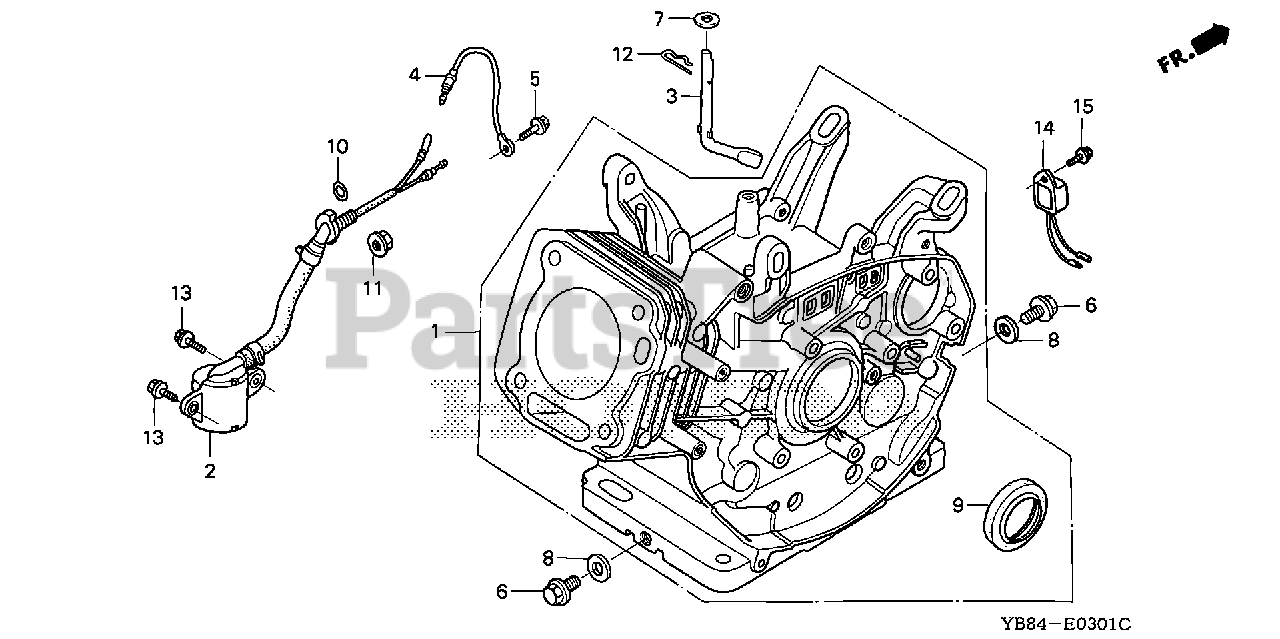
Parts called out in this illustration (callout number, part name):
1	CYLINDER ASSY. (ALERT)
2	SWITCH ASSY., OIL LEVEL
3	SHAFT, GOVERNOR ARM
4	SUB-HARNESS (NOT AVAILABLE)
5	BOLT, FLANGE (6X12) (CT200)
6	BOLT, DRAIN PLUG (12X15)
7	WASHER (8.2X17X0.8)
8	WASHER, DRAIN PLUG (12MM)
9	OIL SEAL (30X46X8)
10	O-RING (13.5X1.5) (ARAI)
10	O-RING (14MM) (NOK)
11	NUT, FLANGE (10MM)
12	PIN, LOCK (10MM)
13	BOLT, FLANGE (6X12)
14	ALERT UNIT, OIL
15	BOLT, FLANGE (6X12) (CT200)
